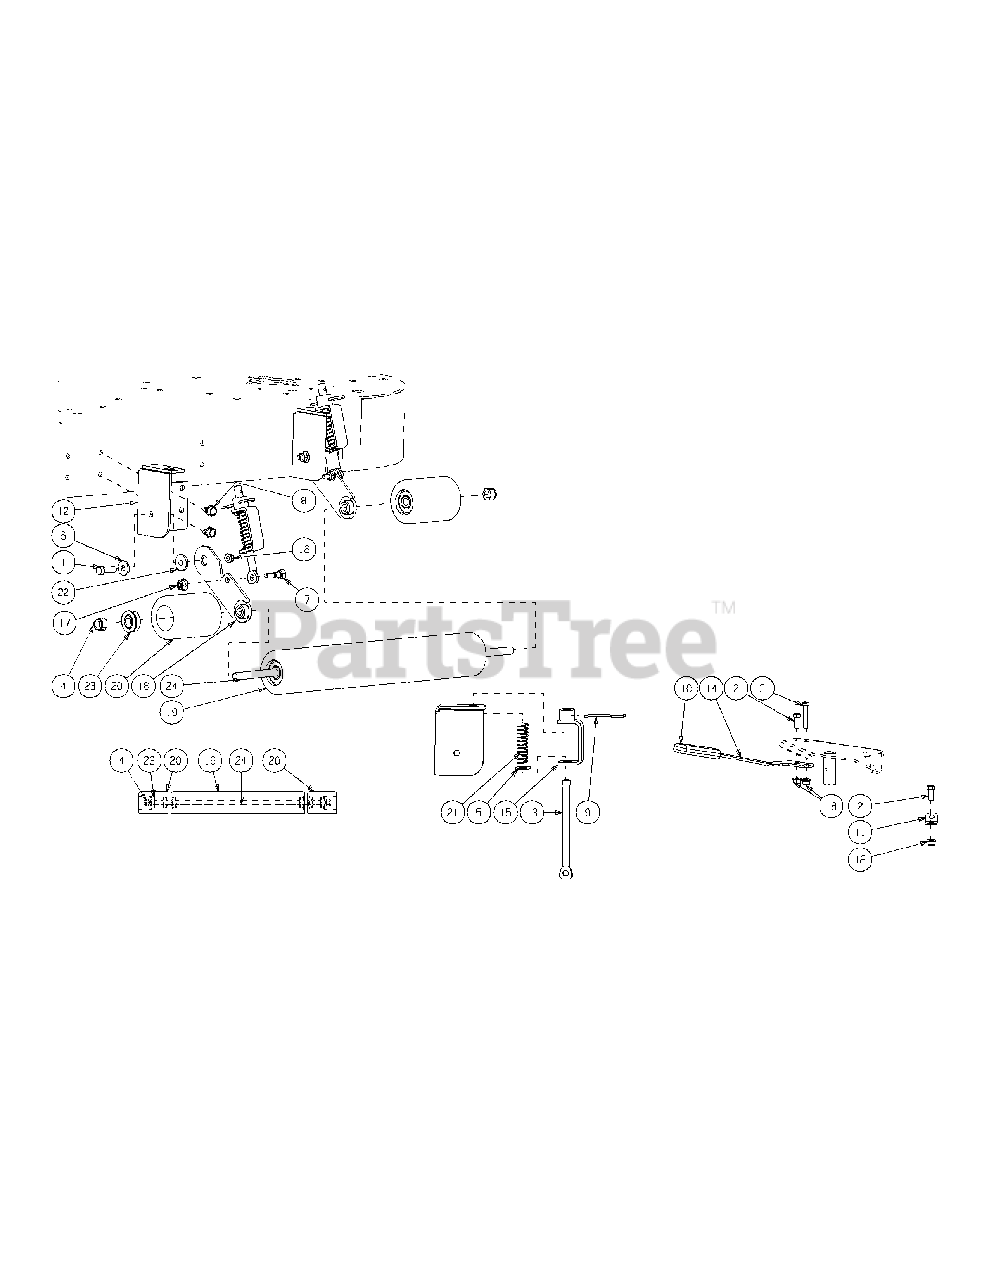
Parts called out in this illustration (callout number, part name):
1	HHCS, 3/8-16 x 1-1/4
2	HHCS, 3/8-16 x 1.00
3	HHCS, 3/8-16 x 2.00
4	Nut, 1/2-13, Nylon Insert
5	Washer, 1/2 Zinc
6	Flat Washer, .406 ID, 1.0 OD,.105
7	Shoulder Bolt
8	Hex Index Washer Screw, 3/8-16, .5
9	HitchPin, .120 Dia. x 3.0
11	Spring Mounting Bracket, 45 degree
12	Striper Mounting Bracket
13	Striper Adjustment Rod
14	Idler Tension Handle
15	Striper Adjustment Clip Assembly
16	Striper Arm Bracket Assembly
17	Nylon Nut, 5/16-18, Flangelock
18	Nylon Nut, 3/8-16, Flangelock
19	Roller, 18.20" w/ Insert
20	Roller, 3.94" w/ Insert
21	Compression Spring, .72 OD x 2.75
22	Shoulder Spacer, .625 Dia. x .190
23	Roller Bearing, .5" ID
24	Striper Roller Rod
